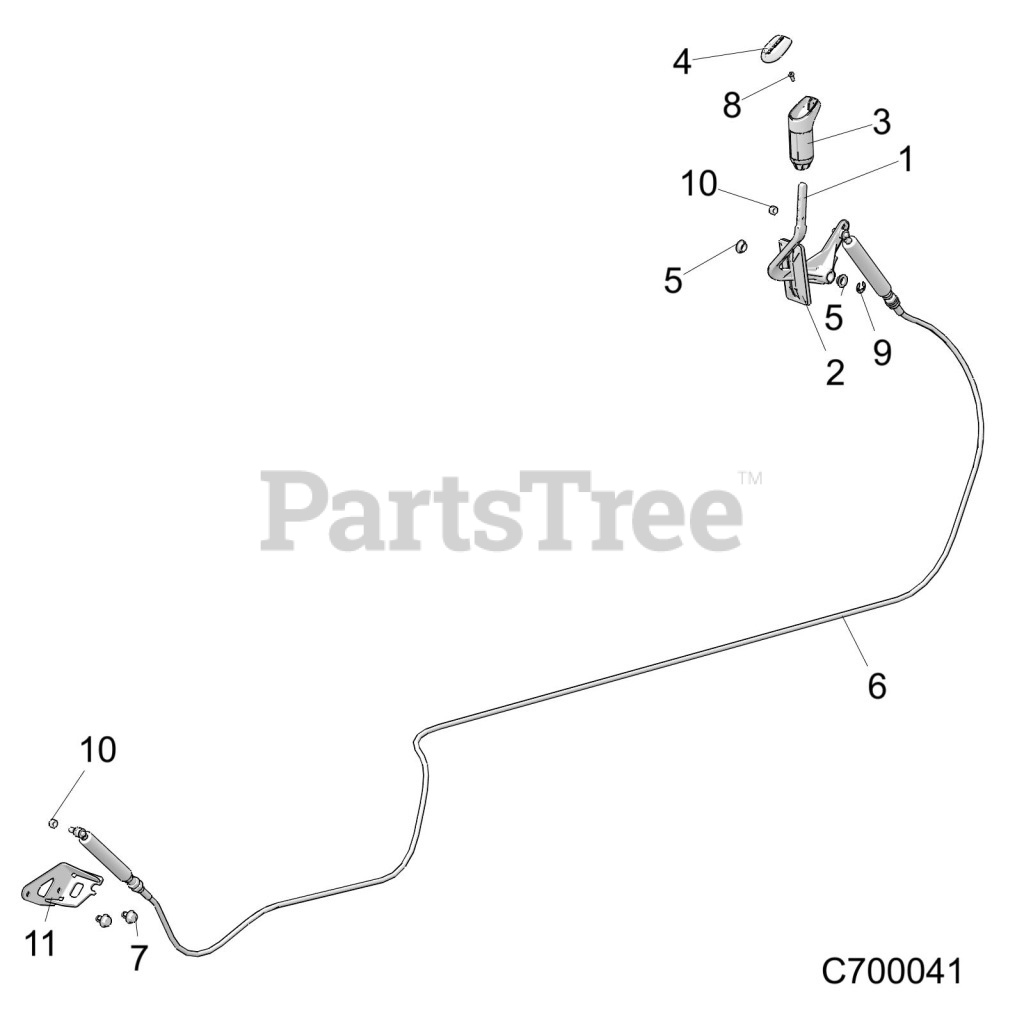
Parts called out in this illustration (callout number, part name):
1	SHIFT-LEVER,CAST,M.BLK
2	GROMMET-SHIFTER
3	KNOB-SHIFTER,BLK
4	COVER-SHIFTER KNOB,BLK
5	BUSHING-PEDAL PIVOT
6	CABLE-SHIFTER,CREW,GAS
7	BOLT-M10X1.25X16,HXHD,FLG
10	NUT,NYLOK M8X1.25(10) *
11	BRKT-CABLE,SHIFT
